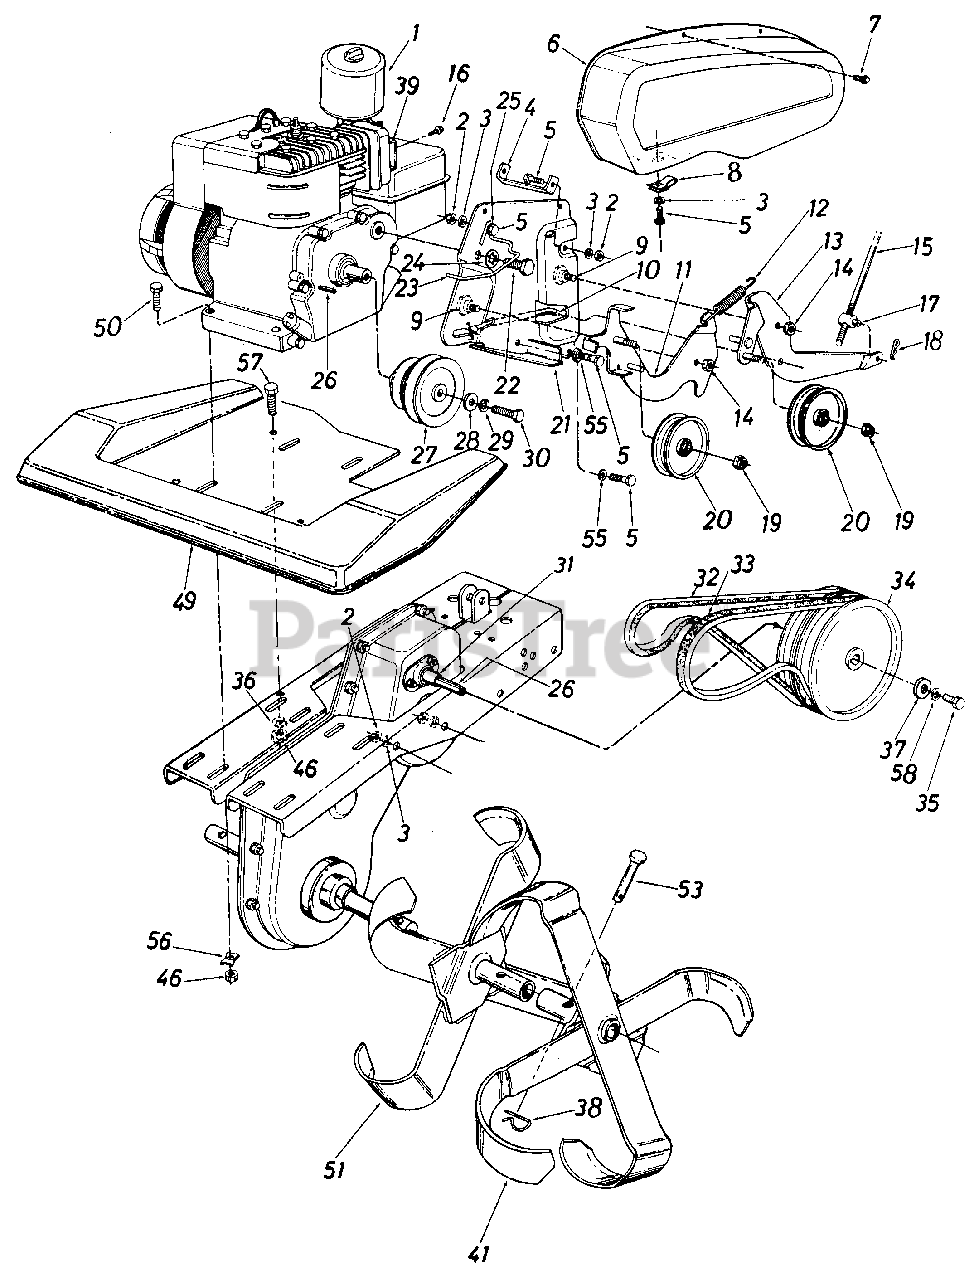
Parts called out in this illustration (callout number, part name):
1	Engine
2	NUT-HEX 1/4-20
3	LOCK WASHER 1/4 DIA
4	BRACKET-SUPPORT
5	SCREW-HEX 1/4-20 x .75
8	NUT-SPEED-1/4-20
9	SCREW-SHLD .625 DIA x .163
10	ROD-CONTROL
11	BRACKET ASSY-IDLER
12	SPRING-TENSION
13	BRACKET ASSY-IDLER
14	NUT-HEX CENTER L-3/8-16
15	ROD-CONTROL-CLUTCH
16	SCREW-HEX WASH HD 10-32 x .38
18	PIN-INTERN COT
19	NUT-HEX CENTER JAM 3/8-24
20	PULLEY-IDLER-FLAT W/FLANGES
21	PLATE-MTG-CLUTCH
22	SCREW-HEX 5/16-24 x .62
23	ROD-BELT GUARD
24	WASHER-LOCK-5/16
25	WASHER-FL
26	KEY-SQ 3/16X1.50
27	PULLEY-ENGINE
28	WASHER-FL-.385 x 1.00 x .135
29	WASHER-LOCK-3/8
30	SCREW 3/8-24 x 1.25 GR5
31	SPACER-.635 ID x .88 OD x 1.03
32	BELT-V 1/2 x 41
33	BELT-V 1/2 x 37 SPECIAL
35	SCREW-HEX 5/16-18 x 10 SPEC
36	WASHER-SPEC L 5/16 x .88 OD
37	WASHER-FL-.312 x 1.125 x .125
38	PIN-COTTER
39	DEFLECTOR-MUFFLER
41	TINE ASSY-INNER-RH
51	TINE ASSY-INNER-RH
55	WASHER-SPRING.270 ID x .51 OD x .030
56	WASHER-SPEC L 5/16 x .88 OD
57	SCREW-HEX 5/16-18 x .75
58	WASHER-LOCK-5/16
